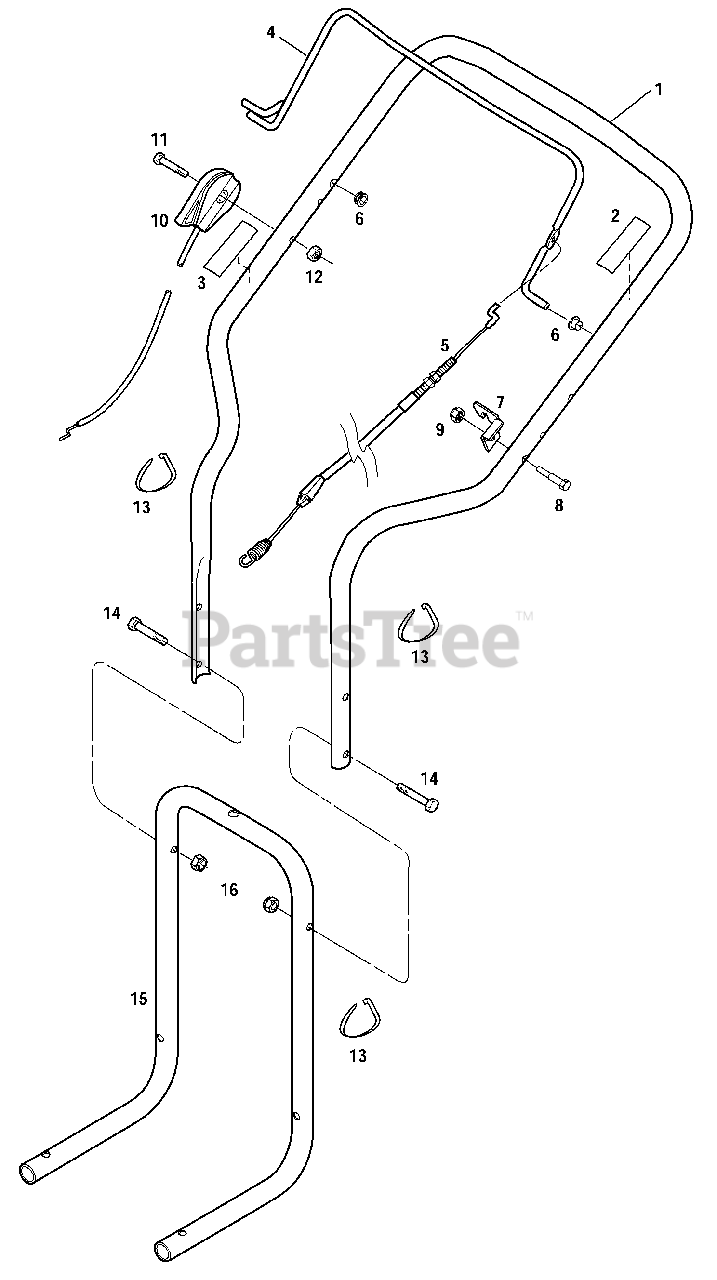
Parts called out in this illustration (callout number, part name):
1	Upper Handlebar
2	Decal-Bail Engage/Disengage
3	Decal-Throttle
4	Control Bail-Trimmer Head
5	Cable Assembly-Trimmer Head
7	Cable Bracket
8	Hex Hd. Screw, 1/4-20 x 1-1/8
9	Hex Flange Lock Nut, 1/4-20
10	Throttle Lever & Cable Assembly
11	Hex Hd. Screw, 1/4-20 x 2
12	Hex Lock Nut, 1/4-20
13	Cable Tie
14	Hex Hd. Screw, 5/16-18 x 1-1/2
15	Lower Handlebar
16	Hex Lock Nut, 5/16-18
